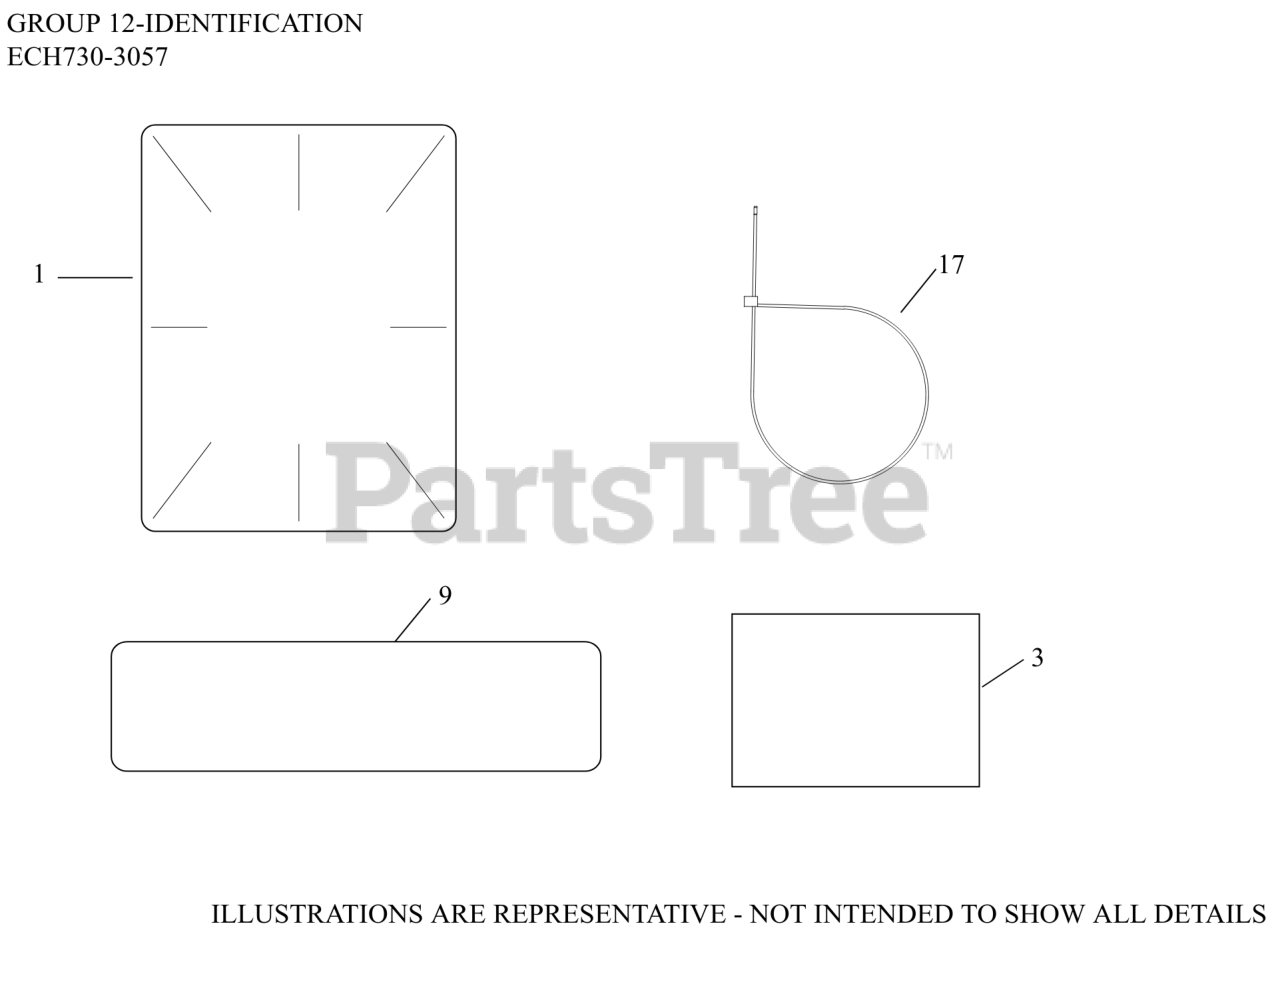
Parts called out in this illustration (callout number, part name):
1	LABEL, CLEAR LAMINATION
3	LABEL, EFI FUEL FILTER
9	DECAL LPAC, 23 HP/747cc/ECV-ECH730
